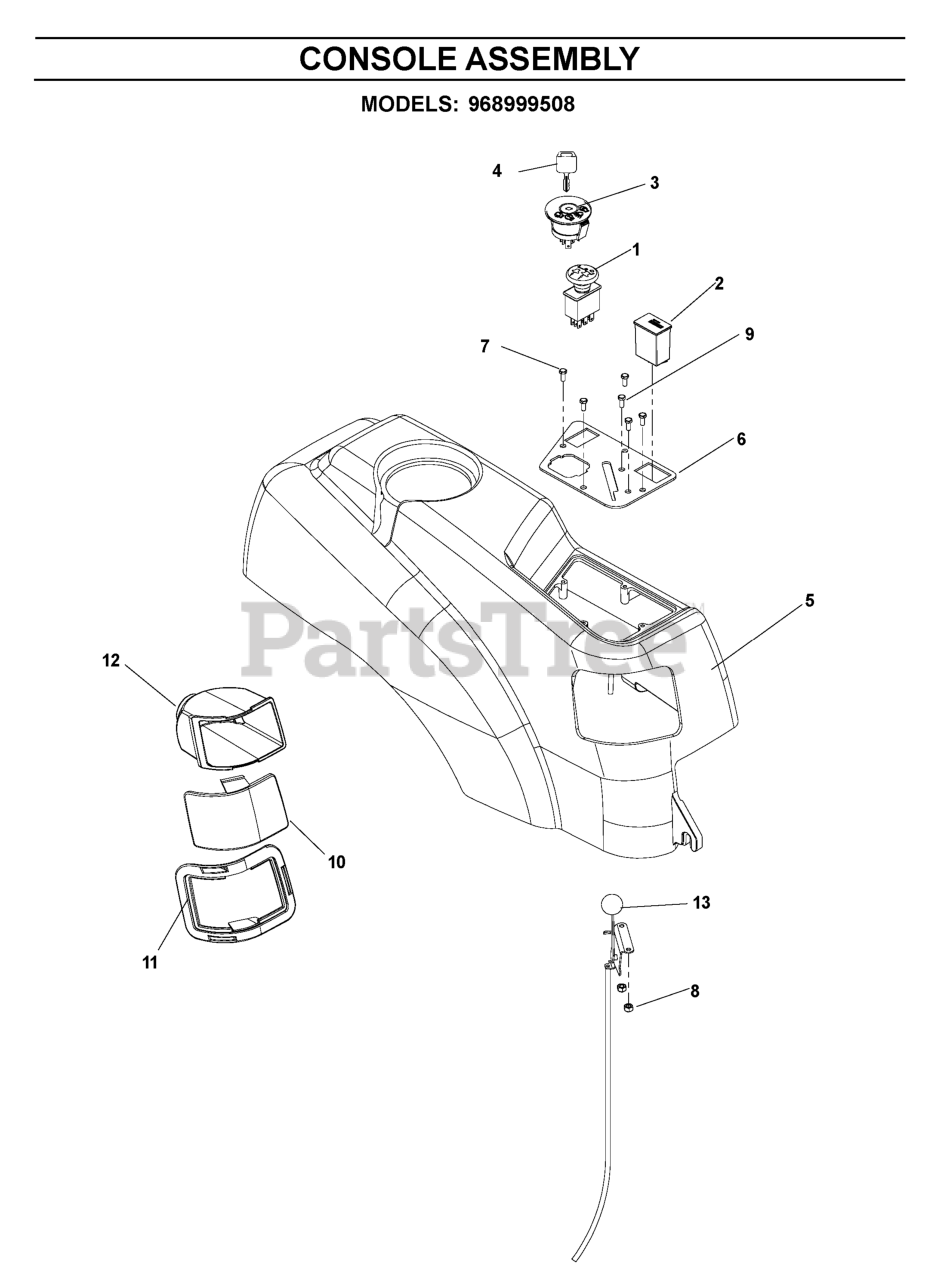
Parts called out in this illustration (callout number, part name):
1	RP.SWITCH, BLADE
2	HOUR METER
3	IGNITION SWITCH
4	KEY
5	FENDER, CONSOLE
6	CONSOLE.PLATE.BLACK
7	SCR #10-12X3/4 HEX WAS HD ZD
8	NUT 10-24 NYLOC
9	HCS #10-24 X 1/2
10	LEFT HEADLIGHT LENS
11	RT HEADLIGHT RIM GREY
12	RT HEADLIGHT REFLECTOR
13	THROTTLE CABLE
